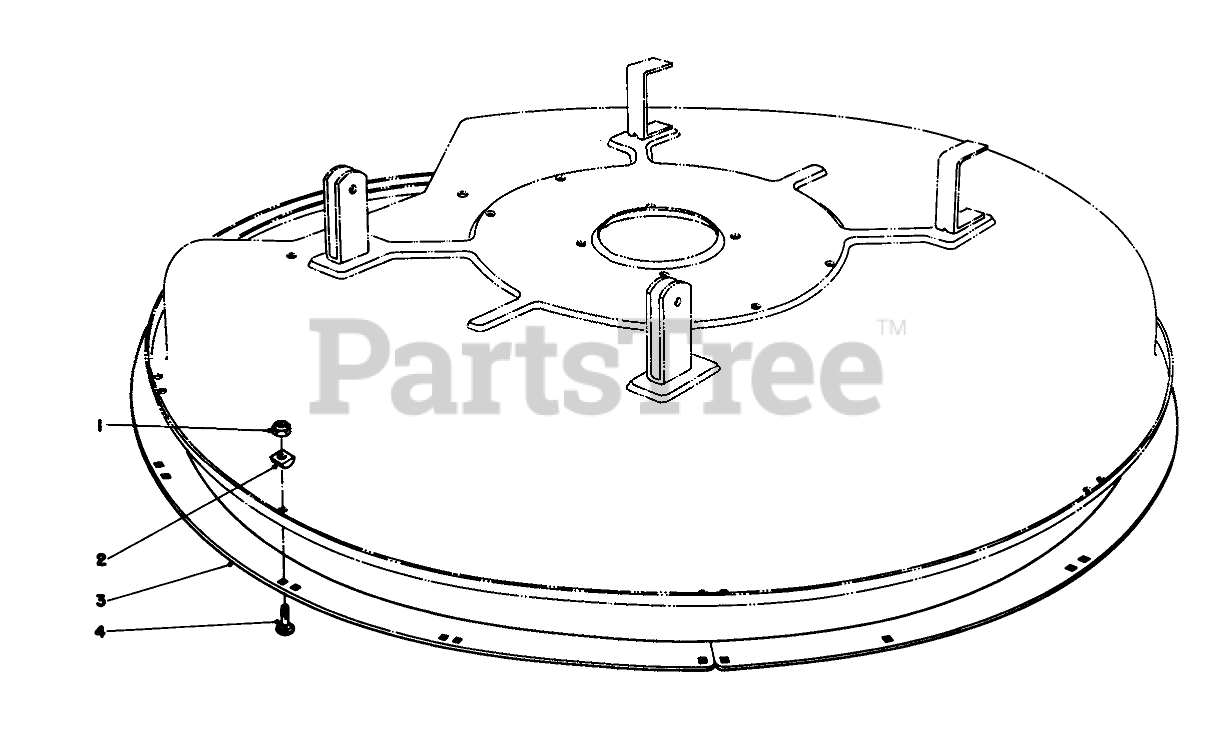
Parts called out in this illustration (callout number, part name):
1	NUT-LOCK, NI
2	Spacer-Deck Ring
3	DECK RING B
4	BOLT-CARR
